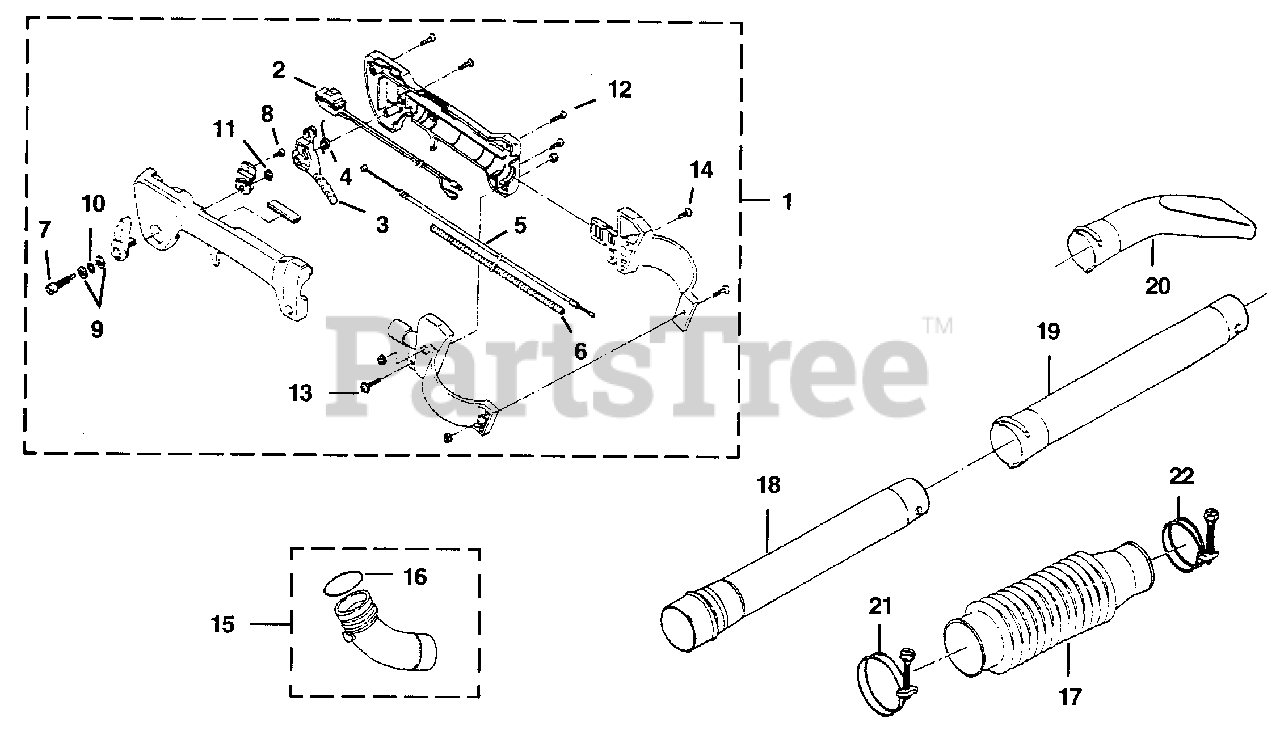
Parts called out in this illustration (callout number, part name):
1	CONTROL LEVER ASSEMBLY
2	SWITCH COMPLETE
3	TRIGGER - Throttle
5	CABLE-Throttle
6	SPIRAL CABLE TUBE
7	SCREW-Socket Hd (M6 x 30)
8	SCREW-Self Tapping (M4 x 8)
10	WASHER-Wave
11	NUT (M6)
12	SCREW-Self Tapping (M4 x 16)
13	SCREW ASSEMBLY (M5 x 25 W SW)
14	SCREW-Pan Hd (M5 x 20)
15	ELBOW COMPLETE
17	TUBE-Flexible
18	TUBE-Upper
19	TUBE-Lower
21	CLAMP-Hose
22	CLAMP-Hose
